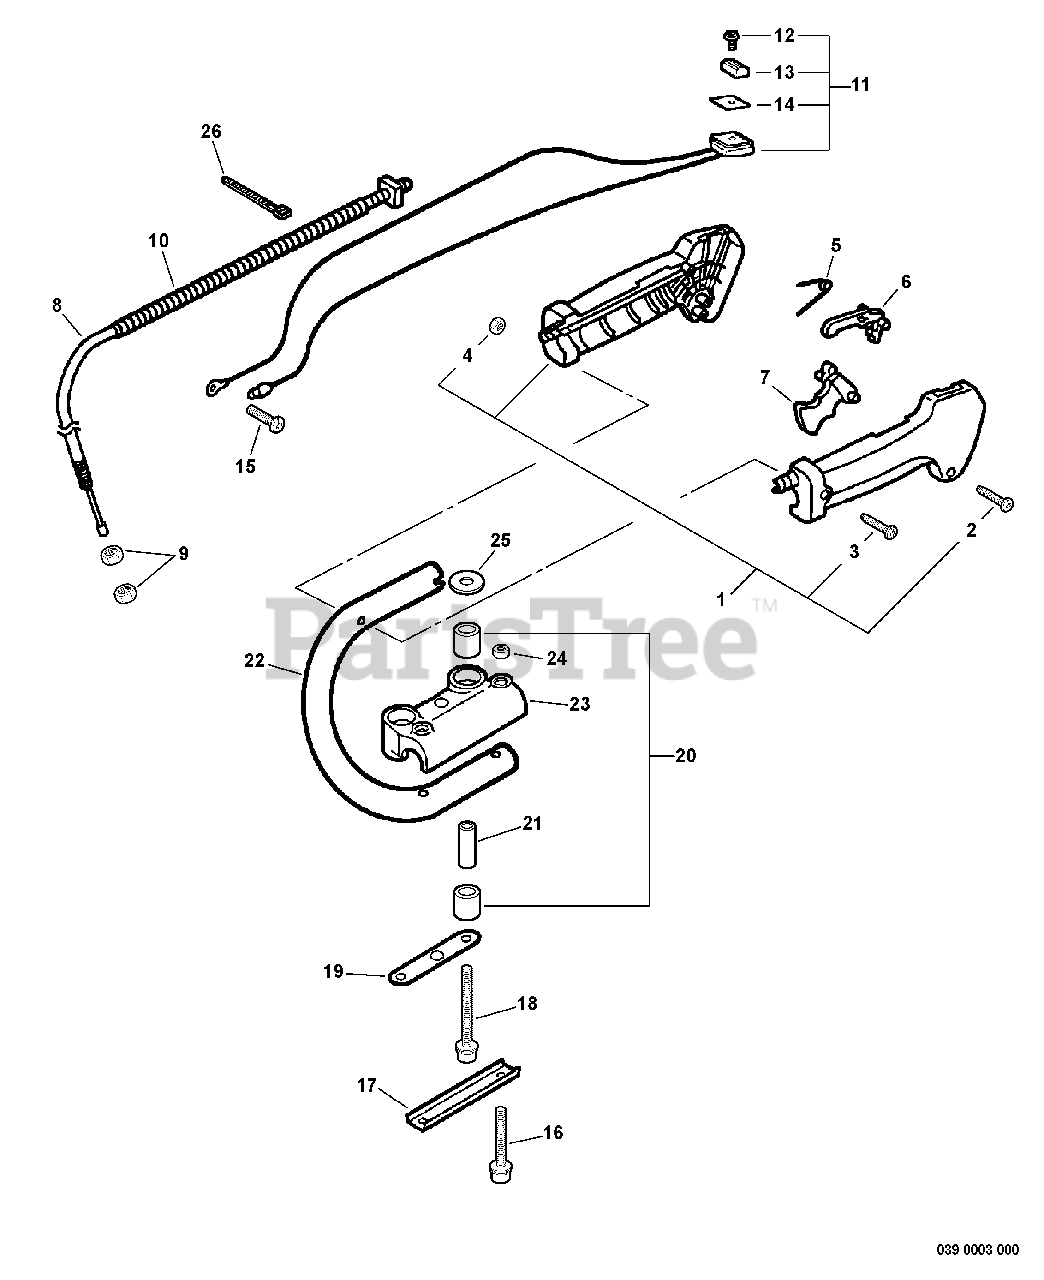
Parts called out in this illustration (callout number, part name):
1	THROTTLE CONTROL ASSY
2	SCREW - 3X25
3	SCREW - 5X30
5	SPRING, LOCKOUT LEVER
6	LOCKOUT, THROTTLE
7	TRIGGER, THROTTLE
8	CABLE, THROTTLE
10	TUBE, PROTECTIVE - CORRUGATED
11	IGNITION SWITCH ASSY
12	SCREW - 3X10
13	KNOB, SWITCH - ORANGE
14	COVER, SWITCH - STOP
15	SCREW - 5X10
16	SCREW - 5X35
17	BRACKET, HANDLE - LOWER
18	SCREW - 5X40
21	SPACER
22	HANDLE - REAR
23	BRACKET, HANDLE - UPPER
26	TIE, CABLE - SMALL
